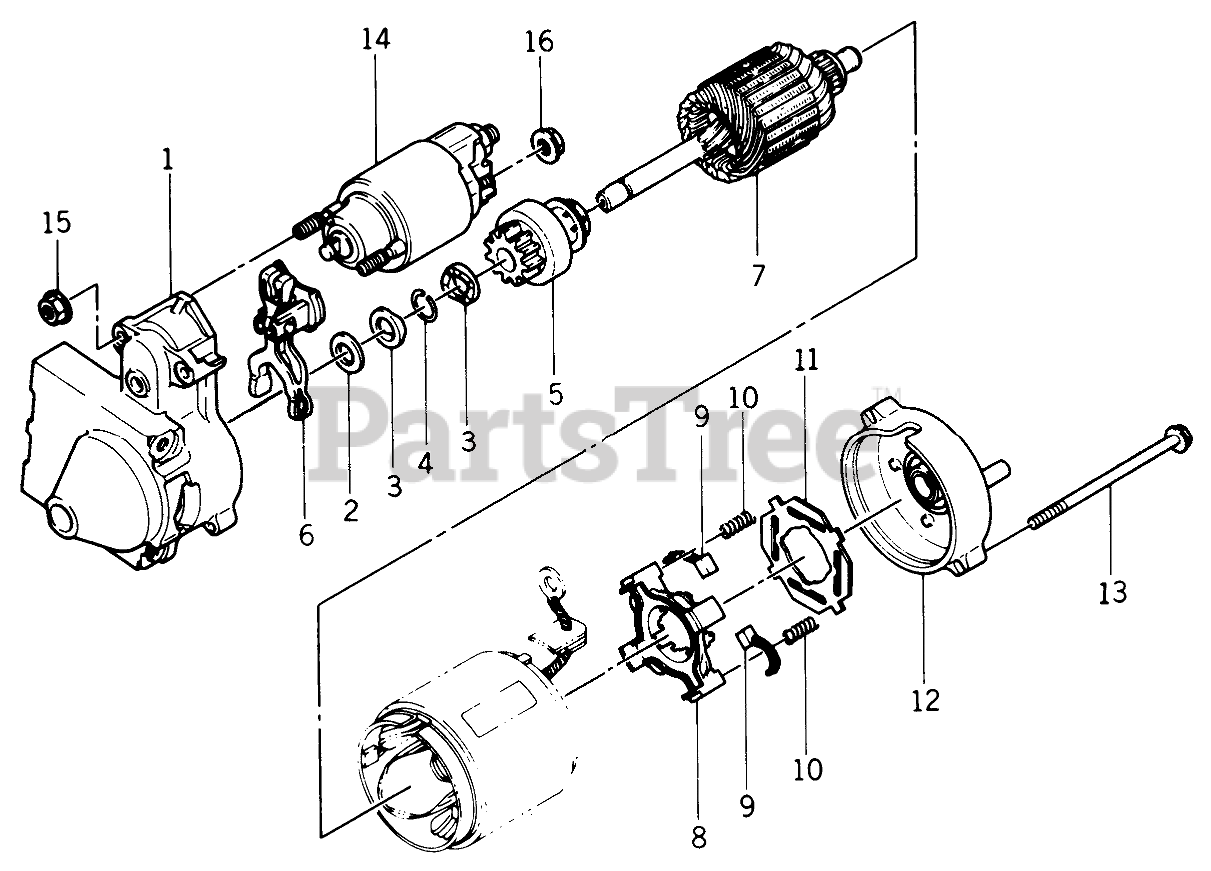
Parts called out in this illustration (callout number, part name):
1	COVER
2	WASHER
3	STOPPER
4	RING-SNAP
5	CLUTCH ASSY
6	LEVER-SHIFT
7	ARMATURE
8	HOLDER-BRUSH
9	BRUSH
10	SPRING-BRUSH
11	INSULATOR
12	COVER ASSY
14	SWITCH ASSY
